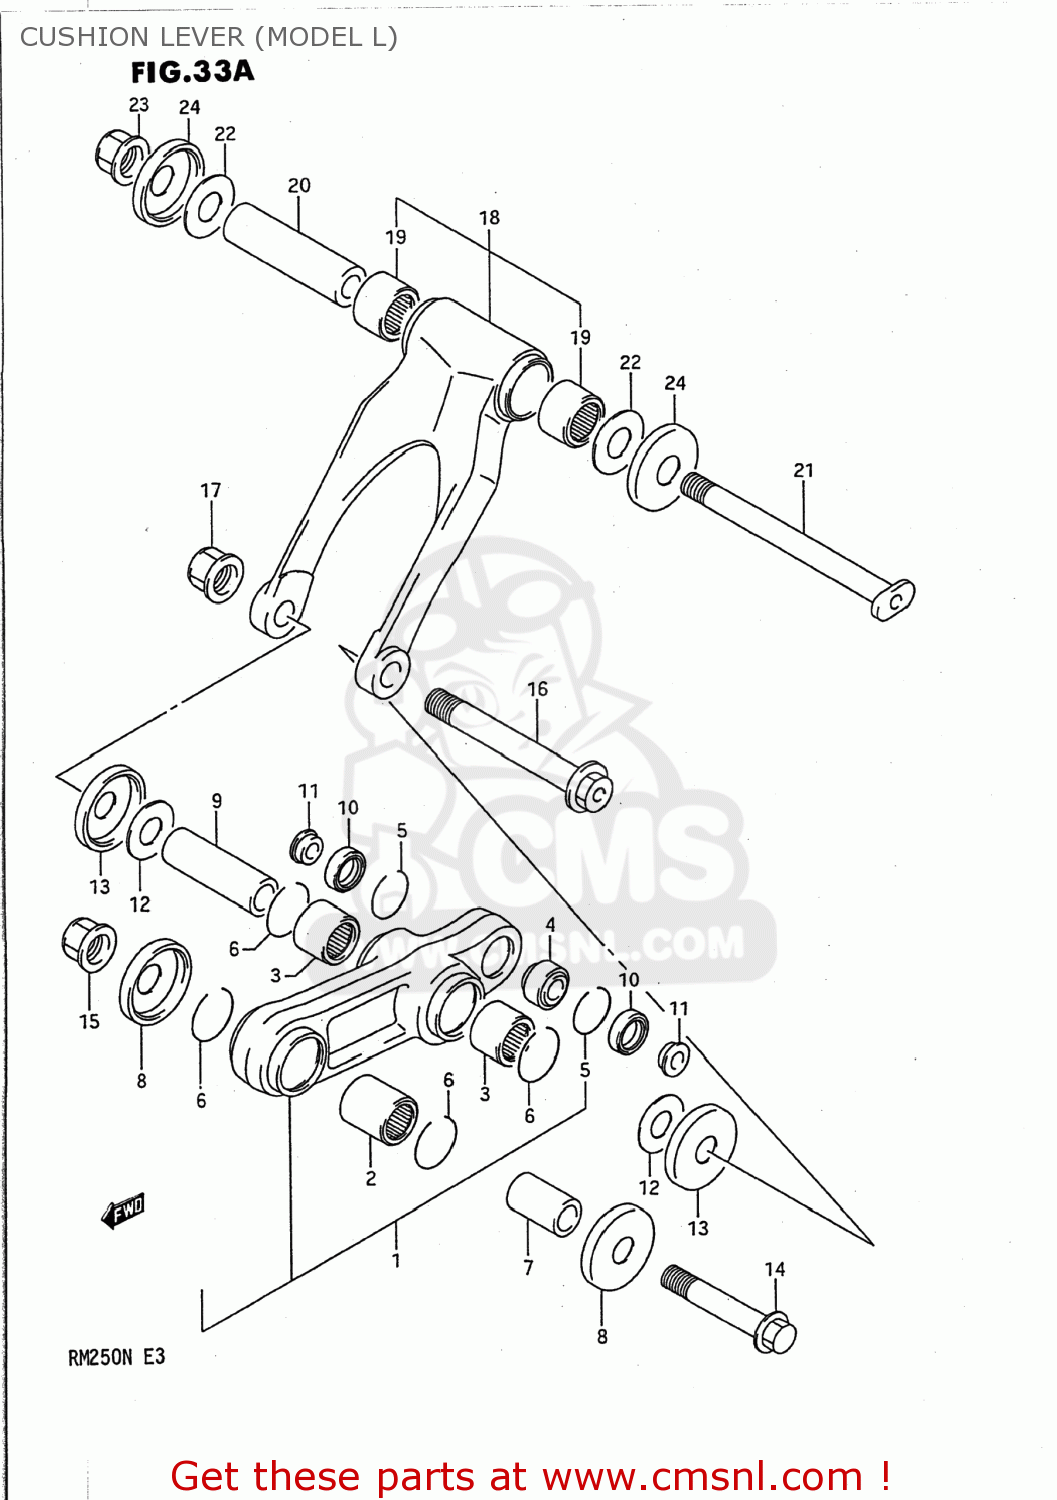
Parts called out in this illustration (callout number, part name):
1	LEVER SET,REAR CUSHION
2	BEARING(20X27X25)
3	BEARING
4	BEARING,RR CUSHION LEVER
5	RING
6	CIRCLIP
7	SPACER,RR CUSHION LEVER FR
8	SEAL,REAR CUSHION LEVER
9	SPACER,RR CUSHION LEVER CTR
10	SEAL,RR CUSHION LEVER RR DUST
11	SPACER,RR CUSHION LEVER RR
12	WASHER
13	SEAL,REAR CUSHION LEVER
14	BOLT,RR CUSHION LEVER FR
15	NUT 12MM
16	BOLT,REAR CUSHION LEVER,CENTER
17	NUT
18	ROD SET,RR CUSHION LEVER
19	BEARING(20X27X25)
20	SPACER,RR CUSHION ROD
21	BOLT,REAR CUSHION ROD
22	WASHER
23	NUT
24	SEAL,RR CUSHION LEVER
